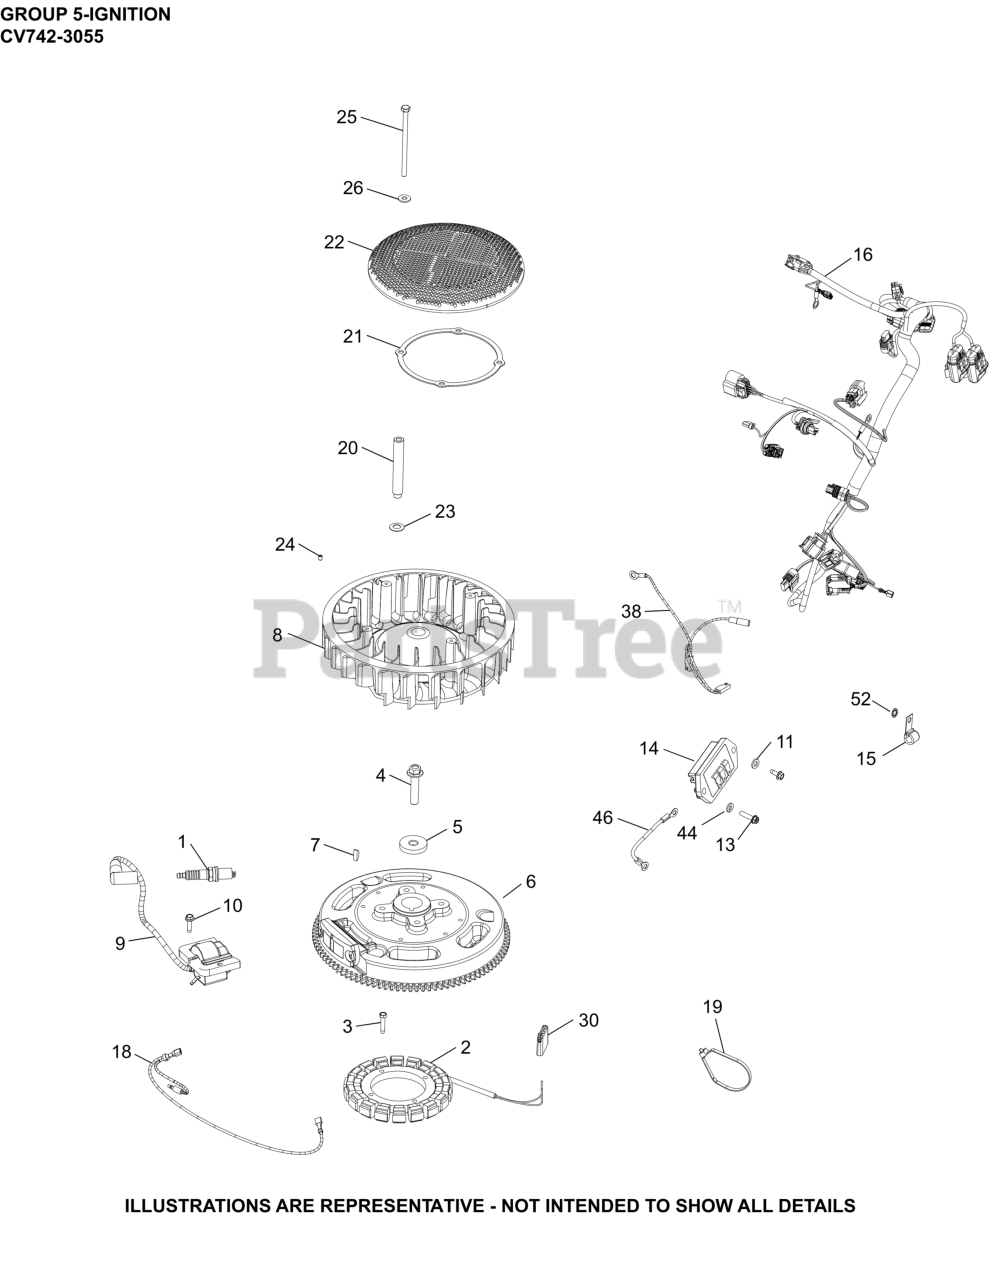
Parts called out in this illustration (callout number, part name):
1	SPARK PLUG, RFI
2	KIT, 15 / 20 AMP STATOR
3	SCREW, THREAD FORMING
4	SCREW, HEX FLANGE
5	WASHER, FLAT
6	FLYWHEEL ASSEMBLY (LW)
7	KEY, 3/16" X 5/8"
9	MODULE, MAGNETO DIGITAL IGNITION
10	SCREW, THD FRM-USE 25 086 473-S
10	SCREW, THREAD FORMING
11	WASHER, FLAT 1/4" (O.D. 1/2")
13	SCREW, HEX FLANGE HI-LO
14	REGULATOR/RECT 12/15A-(#2540345S)
15	CLIP, CABLE
16	HARNESS, WIRING ASSEMBLY
18	HARNESS, LEAD DUPLEX
21	RING, SUPPORT
22	SCREEN, GRASS
23	WASHER, SPRING 10 MM
24	SCREW, SKT SET #10-24X1/4"
25	SCREW, CAP M6X1.0X99.5
26	WASHER, FLAT 1/4" (O.D. 5/8")
30	CONNECTOR
38	LEAD, JUMPER V/S
44	WASHER, LOCK
52	WASHER, INT TOOTH LOCK 1/4"
57	SCREW, THREAD FORMING
64	KIT, REGULATOR RECT (12/15 AMP)
